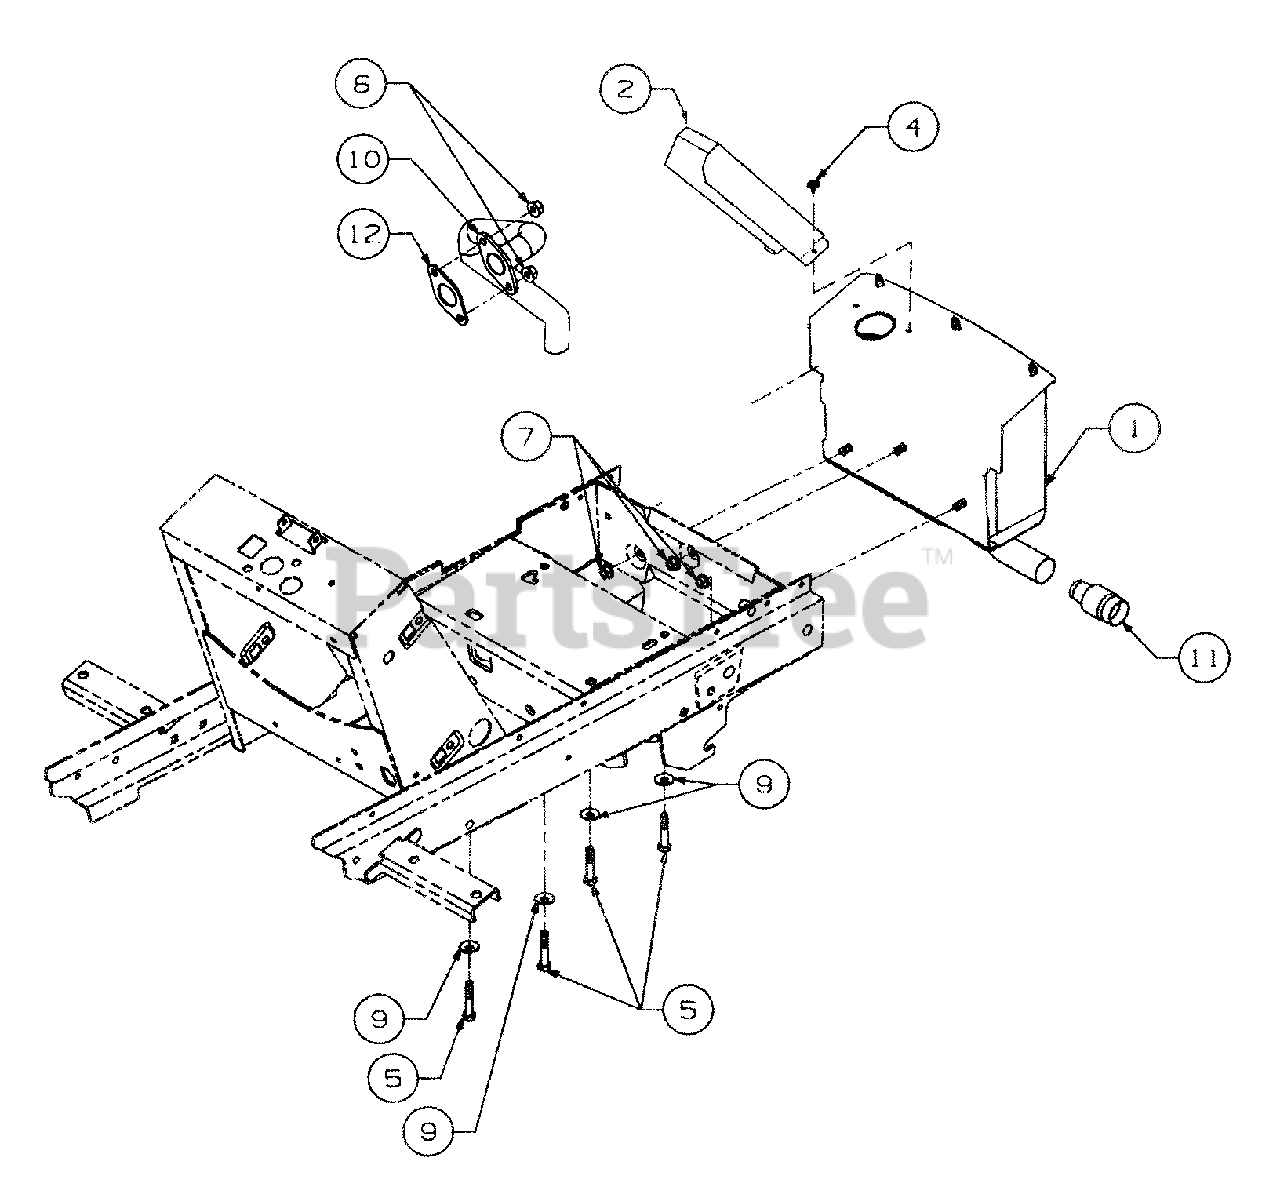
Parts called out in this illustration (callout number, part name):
1	Muffler Assembly
2	Sheild, Muffler Tube
4	Screw, Hex Wsh Hd Tap, #10-16 x .38
5	Bolt, Eng Mount, 3/8-16 x 1.25
6	Nut, Exhaust, M8 x 1.25
7	Nut, Hex Flange Lock, 5/16-18
9	Washer, Bell, .401 x .870 x .063
10	Tube, Exhaust
11	Arrestor, Spark
12	Gasket, Exhaust
